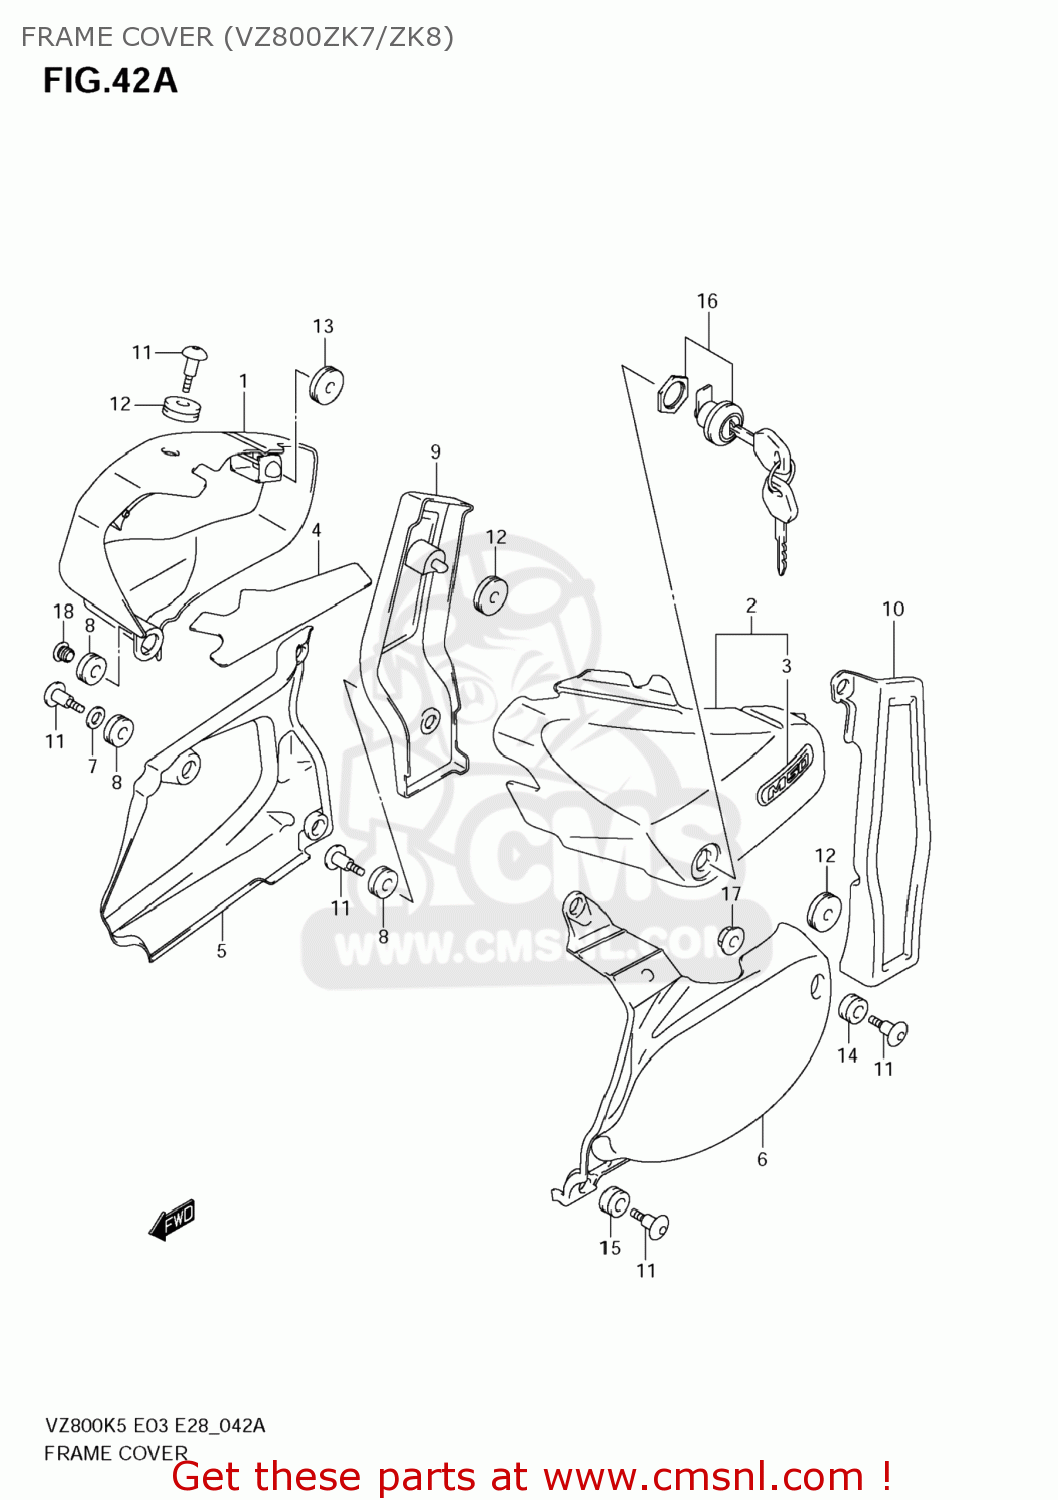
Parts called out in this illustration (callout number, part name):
1	COVER,SIDE,R(GRAY)
2	COVER,SIDE,L(GRAY)
3	EMBLEM,M50
4	SHIELD,FRAME COVER
5	COVER,SIDE LWR,R
6	COVER,SIDE LWR,L
7	WASHER(10.5X20X2.3)
8	CUSHION
9	COVER,SIDE RR,R
10	COVER,SIDE RR,L
11	SCREW(6X20)
12	CUSHION
13	CUSHION
14	CUSHION
15	CUSHION
16	LOCK SET,COVER
17	NUT
18	CAP(OD:14)
